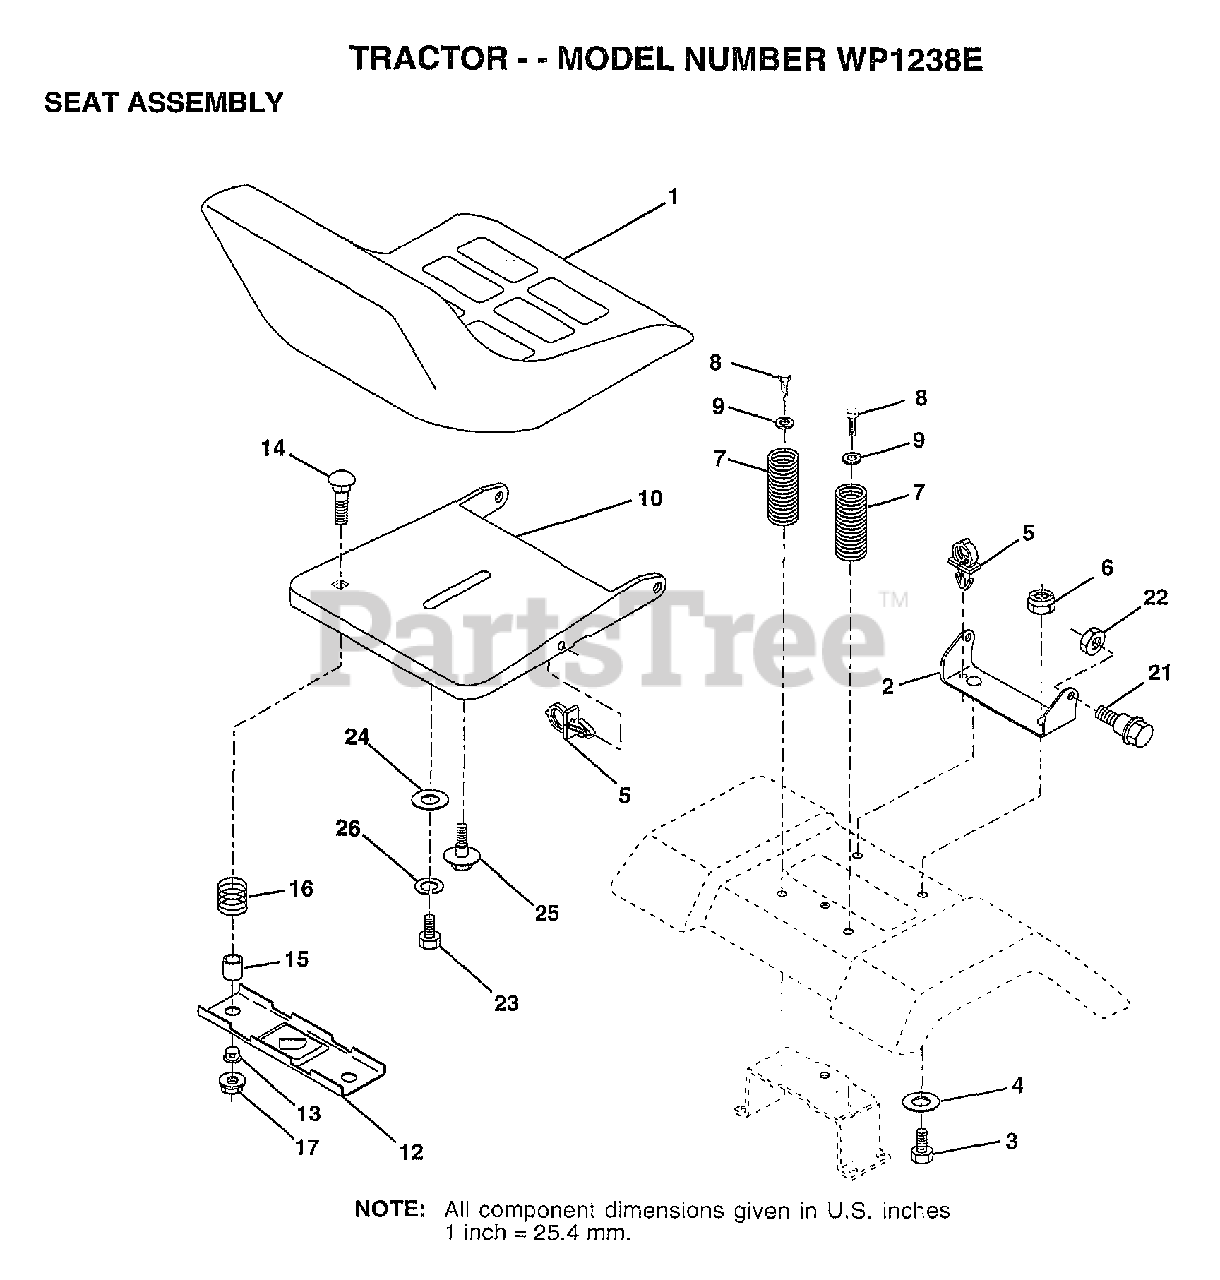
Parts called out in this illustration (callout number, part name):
2	BRACKET PVT SEAT
3	BOLT
4	WASHER PM
5	CLIP.PUSH-IN.HING
6	NUT
7	SPRING COMPRESSIO
8	SCREW GTV
9	WASHER
10	PAN-SEAT
12	BRKT SWITCH
13	BUSHING
14	BOLT-RD HD SQ NK
15	SPLIT SPACER
16	SPRING
21	"BOLT,SHOULDER"
22	NUT
23	BOLT
24	WASHER
25	"BOLT,SHOULDER"
26	LOCKWASHER
